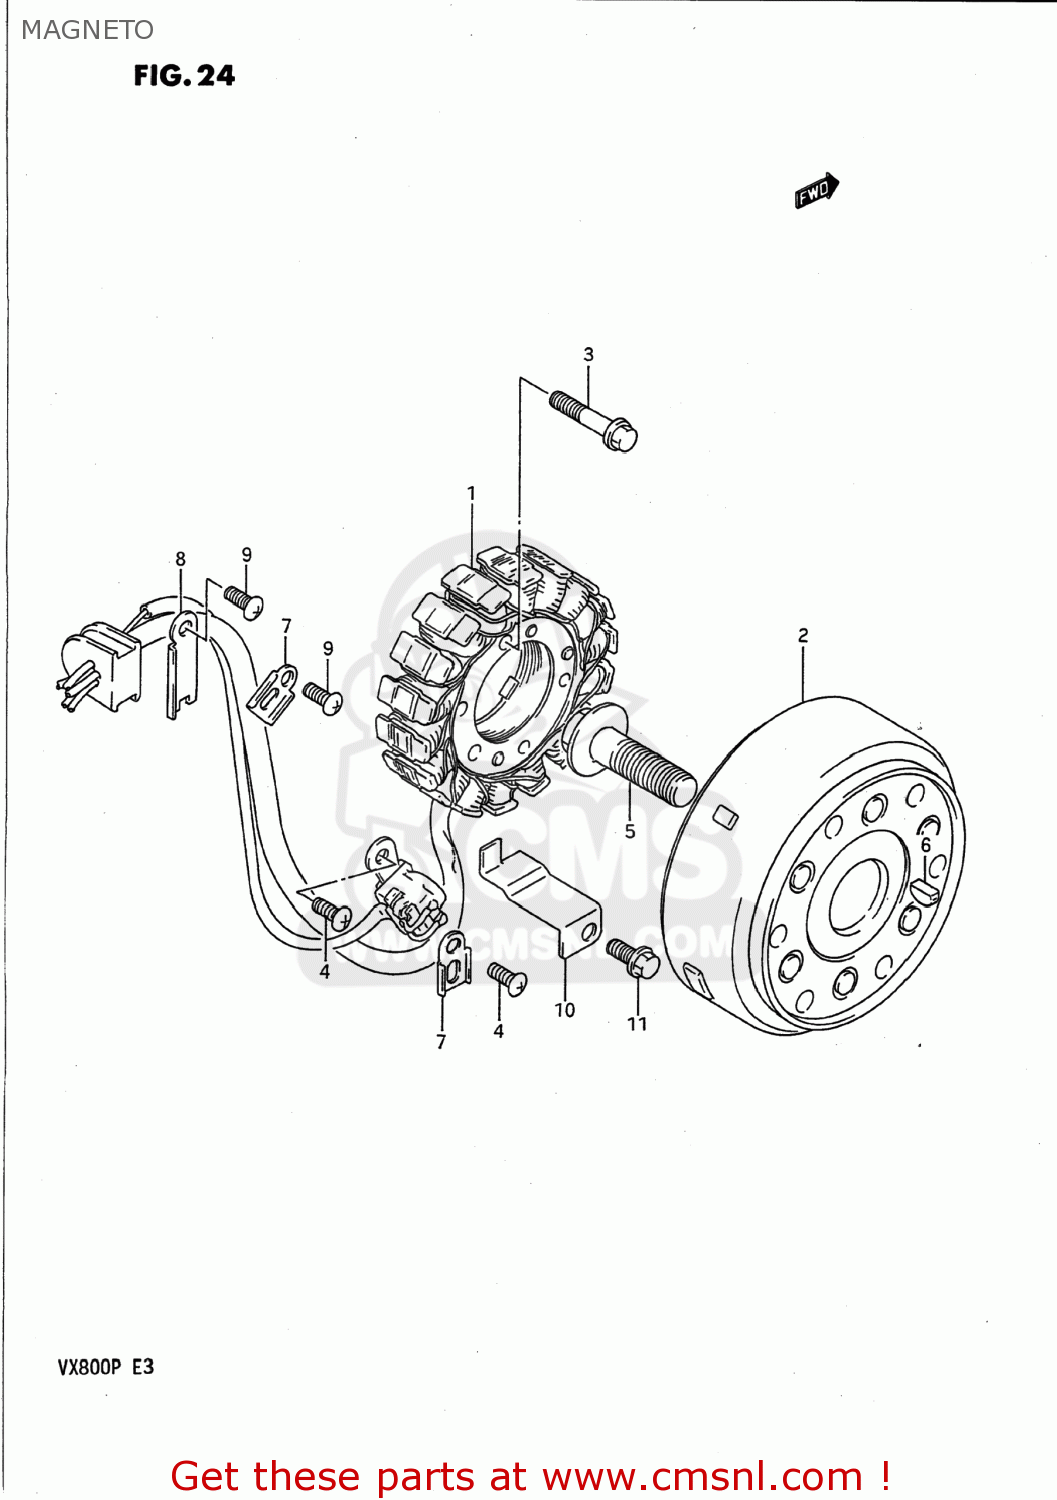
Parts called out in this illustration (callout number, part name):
1	STATOR ASSY
2	ROTOR
3	BOLT
4	SCREW
5	BOLT(14X43)
6	KEY
7	CLAMP,GENERATOR LEAD WIRE
8	CLAMP NO.1,MAGNETO READ WIRE
9	SCREW
10	CLAMP,MAGNETO LEAD WIRE
11	BOLT
